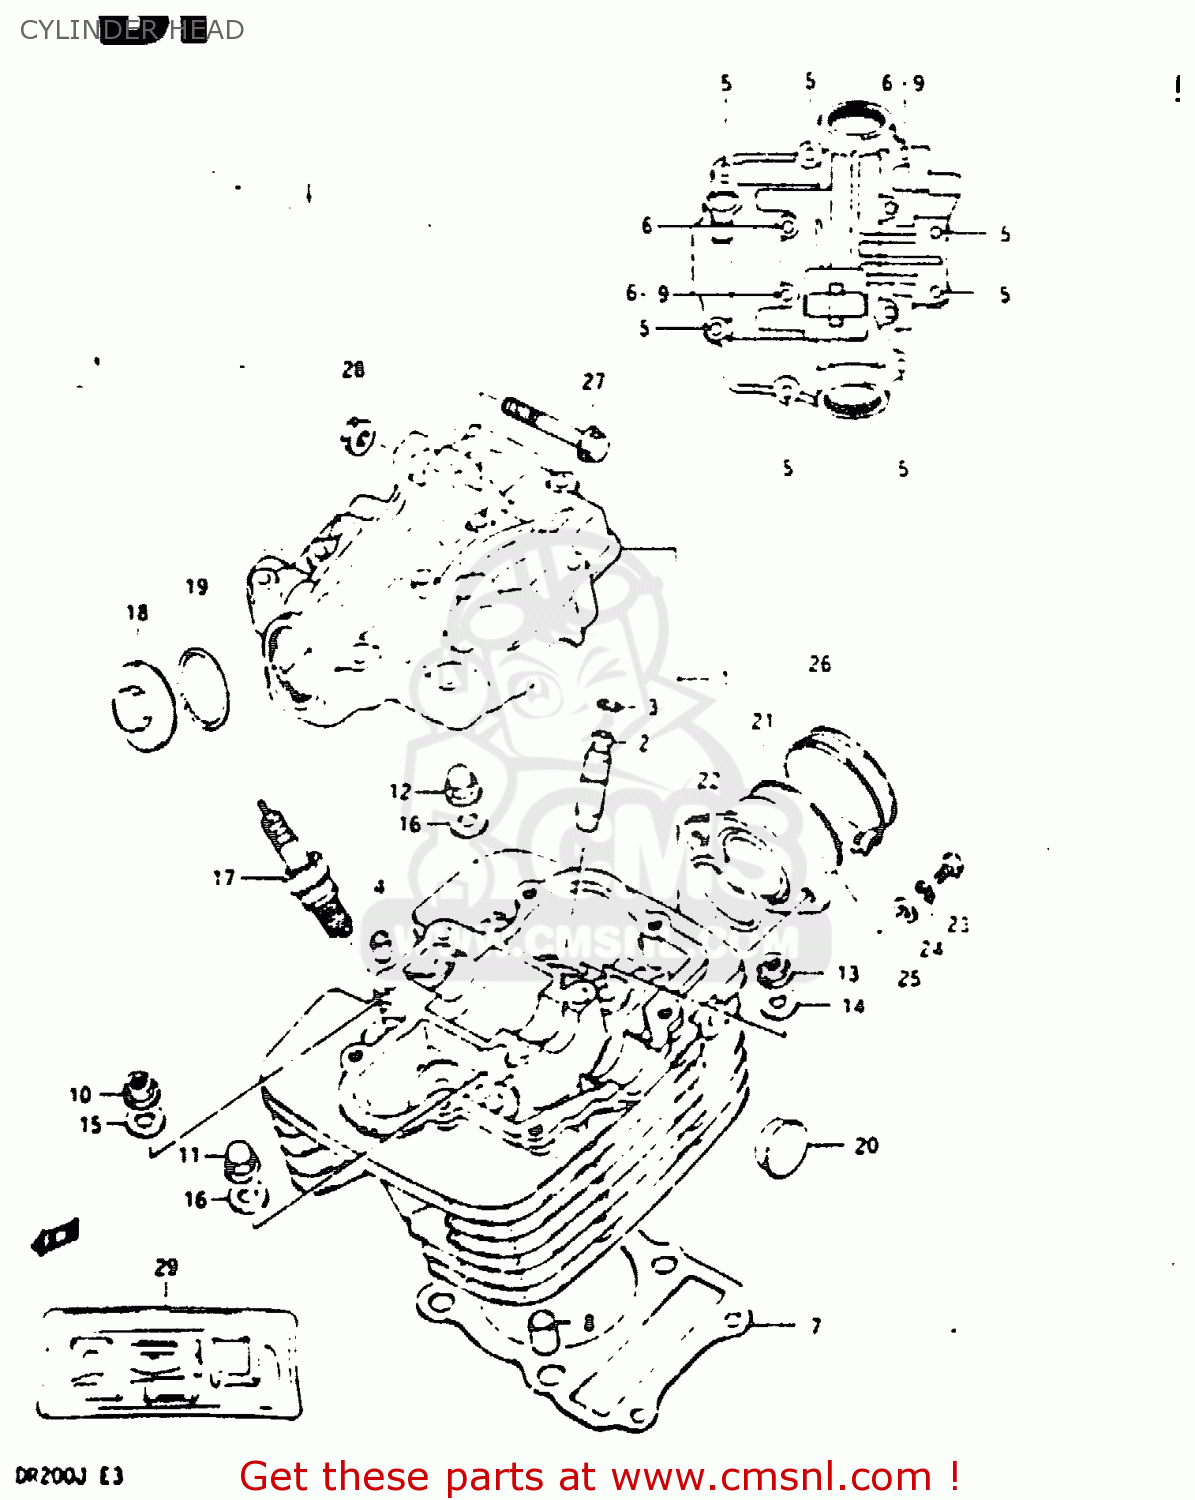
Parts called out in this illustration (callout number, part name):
1	HEAD ASSEMBLY,CYLINDER
2	GUIDE,VALVE
3	RING,SNAP
4	PIN(6.2X8X11)
5	BOLT 6X35
6	BOLT ,6X60
7	GASKET,CYLINDER HEAD (NAS)
8	PIN
9	WASHER
10	NUT 8MM
11	NUT (8MM)
12	NUT
13	NUT
14	WASHER (8.5X19X2.3)
15	WASHER(8.5X19X2.3)
16	GASKET (NAS)
17	SPARK PLUG D8EA
18	CAP,INSPECTION
19	O RING(D:3,ID:29.5)
20	PLUG(OD:22.5)
21	PIPE,INTAKE
22	O-RING,INTAKE PIPE
23	SCREW
24	WASHER,LOCK
25	WASHER
26	CLAMP
27	BOLT 8X50
28	NUT
29	GASKET SET
